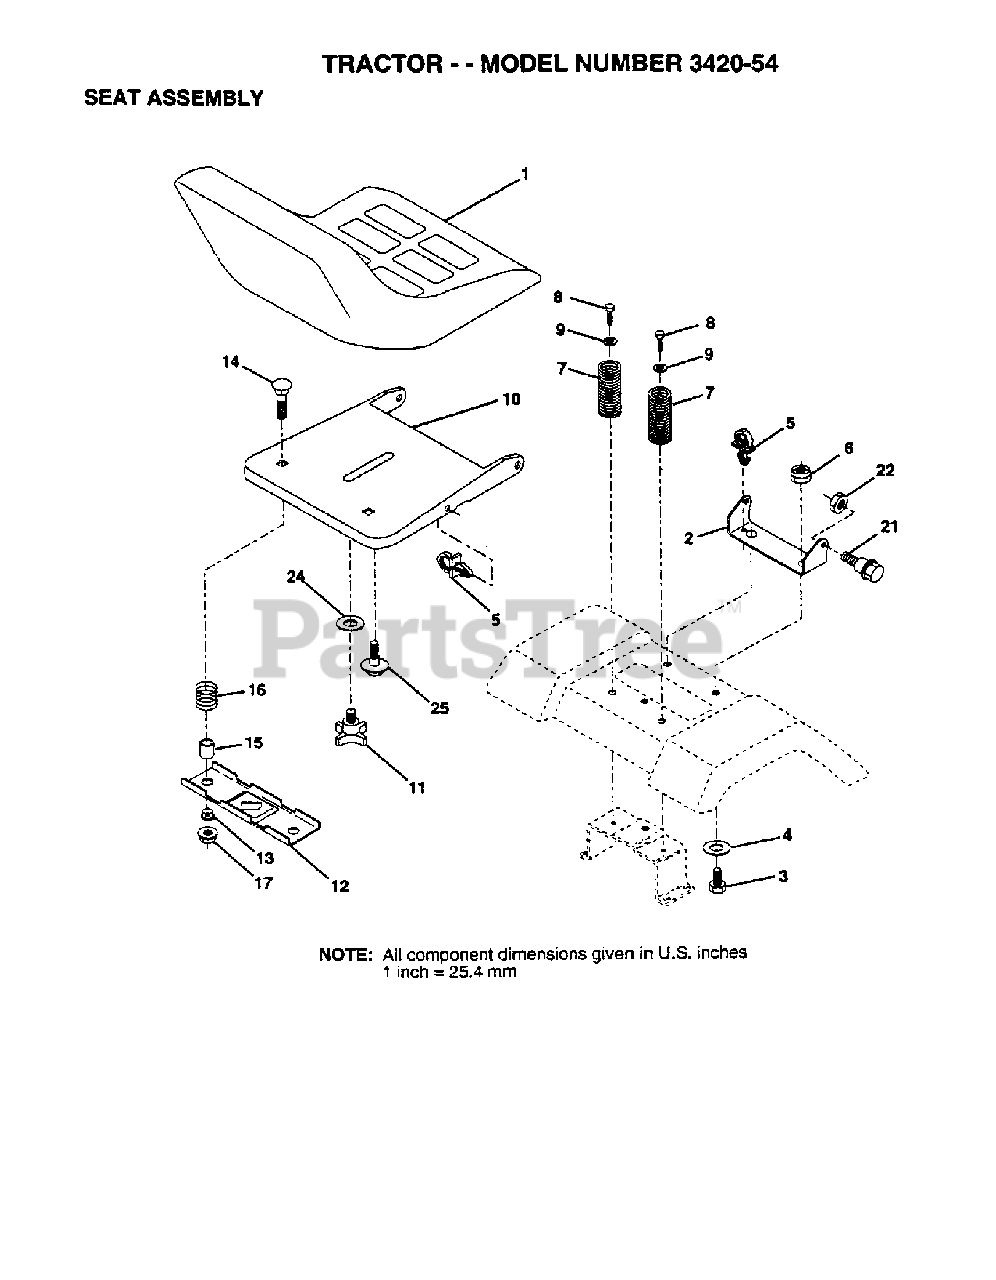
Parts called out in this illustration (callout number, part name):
2	BRKT,SEAT PIVOT**
3	BOLT
4	WASHER PM
5	PUSH CLIP
6	NUT
7	SPRING COMPRESSION
8	SCREW GTV
10	PAN SEAT
12	BRKT SWITCH
14	BOLT CARRIAGE 1/4-20X1 3/8
15	SPACER SPLIT
16	SPRING COMPRESSED
17	NUT T
21	BOLT, SHOULDER LT
22	LOCKNUT
25	BOLT, SHOULDER**
